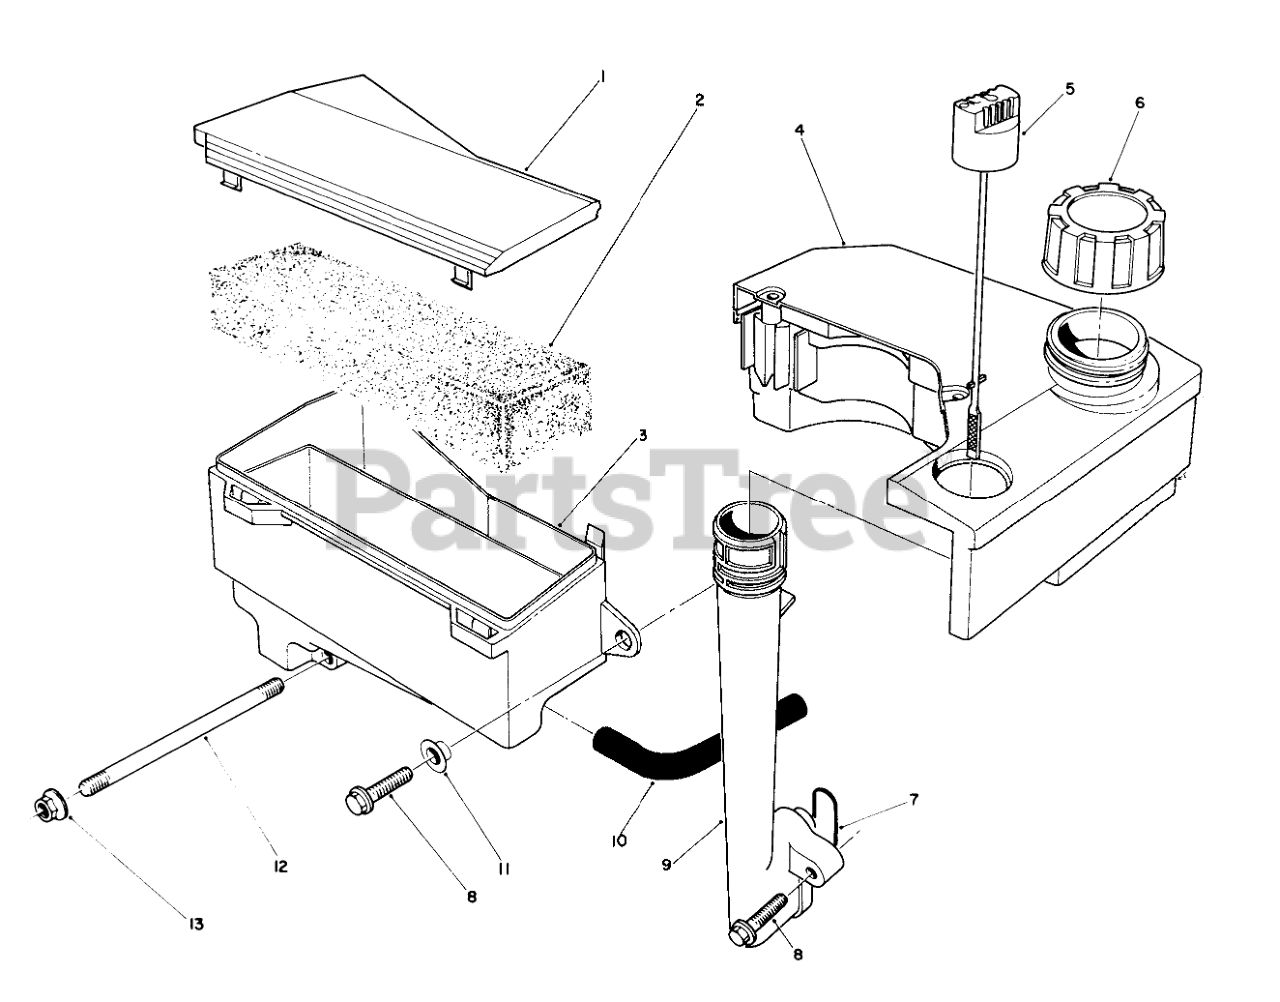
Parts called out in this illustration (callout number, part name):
1	AIR CLEANER CAP
3	Body-Air Cleaner
4	TANK ASM
5	Dipstick
6	GAS CAP ASM
7	O-RING
11	SPACER
12	Stud-Carburetor
